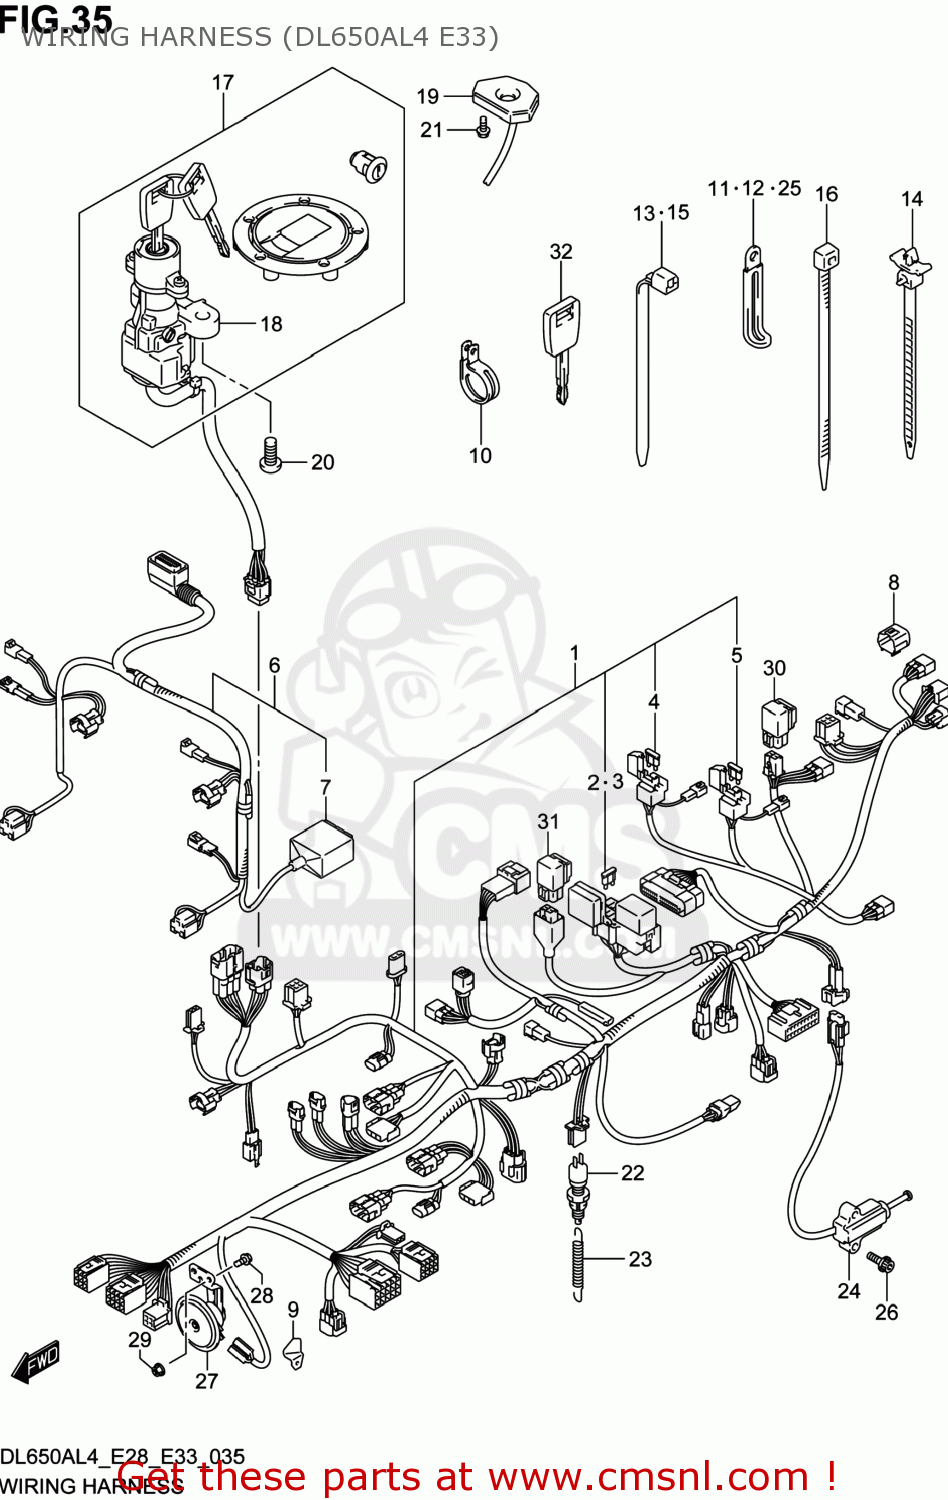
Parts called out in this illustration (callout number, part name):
1	HARNESS,WIRING NO.1
2	FUSE(10A)
3	FUSE(15A)
4	FUSE(15A)
5	FUSE(25A)
6	HARNESS,WIRING NO.2
7	COVER,CONNECTOR
8	CAP,TS
9	GUIDE,WIRING HARNESS
10	CLAMP
11	CLAMP(L:45)
12	CLAMP(L:80)
13	CLAMP(L:125)
14	CLAMP(L:120)
15	CLAMP(L:165)
16	CLAMP(L:145)
17	LOCK SET
18	LOCK ASSY,STEERING
19	COVER,STEERING LOCK
20	BOLT(8X20)
21	BOLT
22	SWITCH ASSY,STOP LAMP
23	SPRING
24	SWITCH ASSY,SIDE STAND
25	CLAMP(L:45)
26	BOLT
27	HORN ASSY
28	BOLT(6X16)
29	NUT
30	RELAY ASSY
31	RELAY ASSY
32	KEY,BLANK
